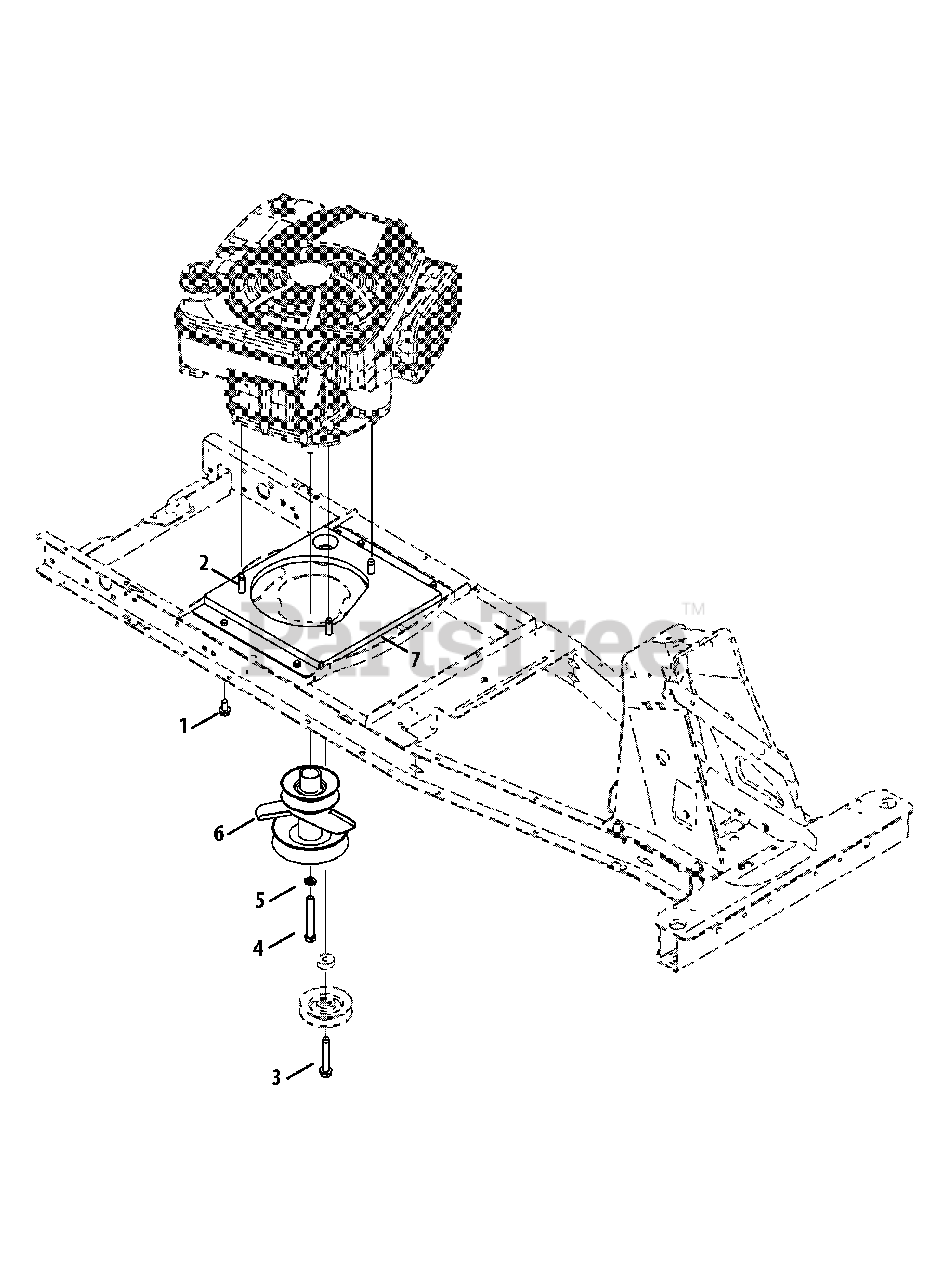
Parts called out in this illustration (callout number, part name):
1	Tap Screw, 5/16-18, .750
2	Tap Screw, 3/8-16, 1.000
3	Tap Screw, 3/8-16, 2.250
4	Hex Cap Screw, 3/8-24 x 2.75
5	Lock Washer, 3/8
6	Engine Pulley
7	Engine Mounting Plate
